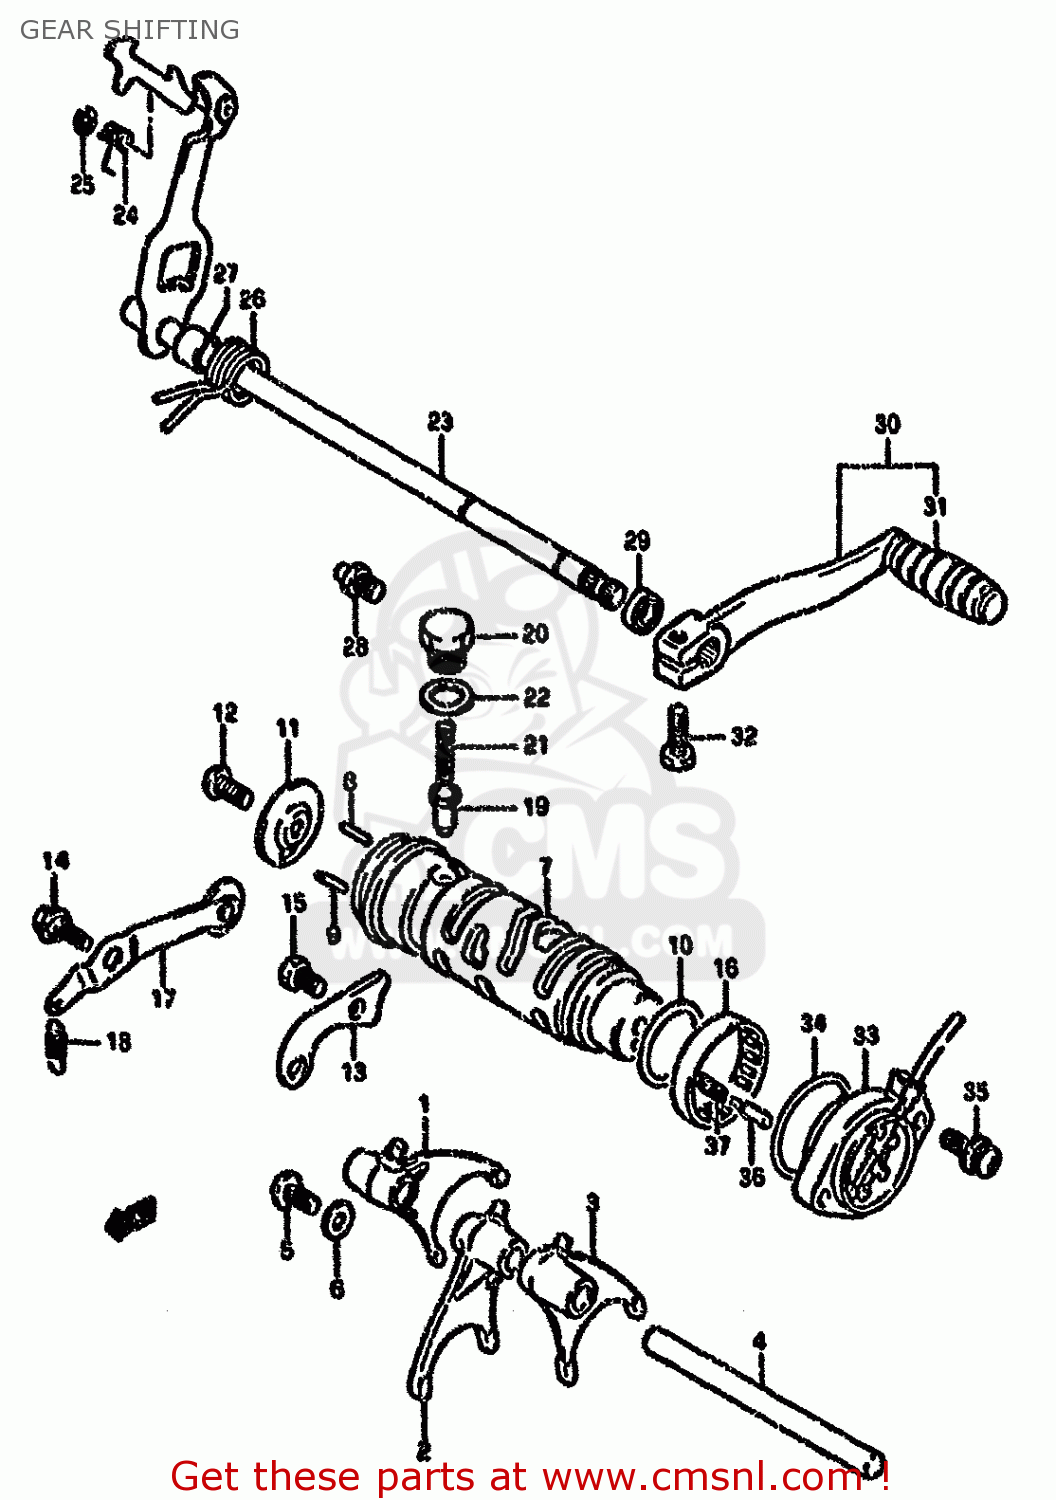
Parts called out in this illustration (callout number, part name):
1	FORK,GEAR SHIFT NO.1
2	FORK,GEAR SHIFT NO.2
3	FORK,GEAR SHIFT NO.2
4	SHAFT,GEAR SHIFT FORK
5	SCREW
6	WASHER
7	CAM,GEAR SHIFT
8	PIN(4X18.5)
9	PIN
10	SHIM(26X32.5X0.3)
11	RETAINER,GEAR SHIFT CAM DR PIN
12	SCREW 6X16
13	GUIDE,GEAR SHIFT CAM
14	BOLT
15	BOLT
16	BEARING(40X47X12)
17	STOPPER,GEAR SHIFT CAM NO.1
18	SPRING
19	STOPPER,GEAR SHIFT CAM NO.2
20	HOLDER,GEAR SHIFT CAM STOP SPR
21	SPRING
22	GASKET(14X19.2X2) (NAS)
23	SHAFT,GEAR SHIFT
24	SPRING
25	E RING
26	SPRING
27	SPACER(12X20X15.3)
28	STOPPER,GEAR SHIFT CAM
29	OIL SEAL
30	LEVER ASSY,GEAR SHIFT
31	RUBBER,GEAR SHIFT PEDAL
32	BOLT
33	BASE ASSY,NEUTRAL SW TERMINAL
34	O-RING (D:2.4 ID:26.2)
35	SCREW
36	PIN(5X15.5)
37	SPRING
